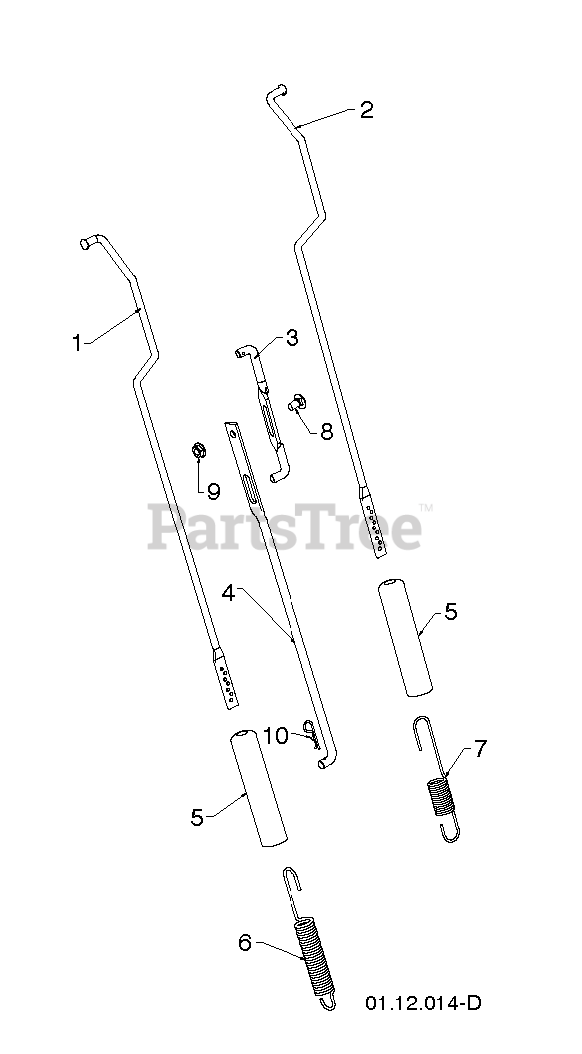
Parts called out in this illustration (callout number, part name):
1	ROD.IMPELLER
2	ROD.TRACTION
3	ROD.SHIFTER.TOP.HYD
4	ROD, LOWER, SPEED CONTROL
5	SLEEVE, SPRING
6	SPRING.CONTROL.ROD.SNOW
7	SPRING.TRACTION.ROD.SNOW
8	BOLT
9	NUT.FLANGE.5/16
10	SPRING RETAINER
